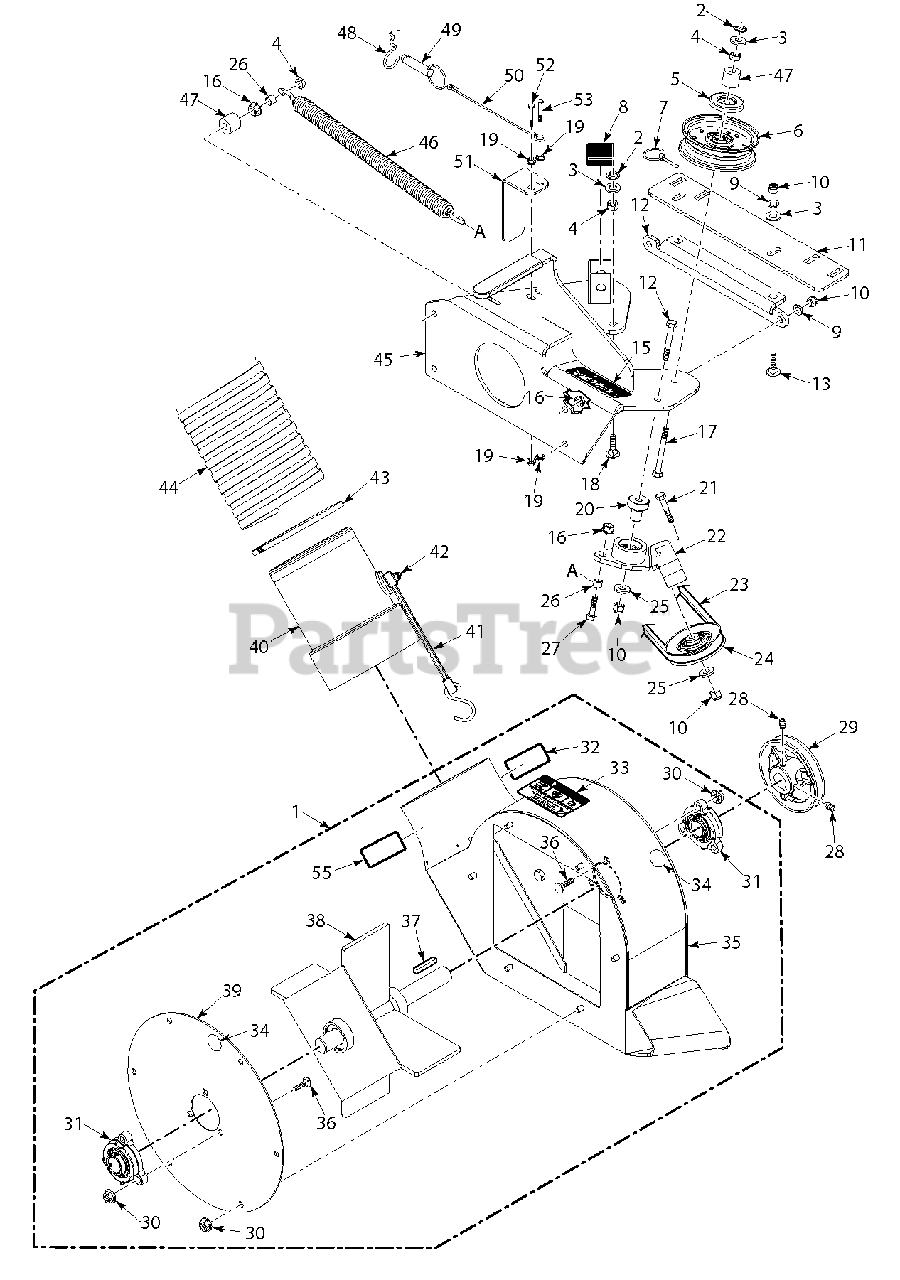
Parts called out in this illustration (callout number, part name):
1	Blowing Housing Assembly w/Fan
2	Nut, Push-On
3	Flatwasher, 3/8-.391 x .938 x .105
4	Nut, Center Lock 3/8-16
5	Dust Shield
6	Pulley, 4" Idler
7	Quick Pin
9	Lockwasher, 3/8" Spring
10	Nut, Elastic Stop 3/8-16
11	Plate, Blower Catch
12	Plate, Catch Mounting
13	Bolt, Carriage 3/8-16 x 1-1/4"
14	Bolt, Hex Head 3/8-16 x 2-1/4"
15	Decal, Belt Cover
16	Nut, Serrated Flange 3/8-16
17	Bolt, Hex Head 3/8-16 x 3-1/2" Full Thread
18	Bolt, Carriage 3/8-16 x 1-1/2"
19	Nut, Serrated Flange 1/4-20
20	Pivot, Idler
21	Bolt, Hex Head 3/8-16 x 2"
22	Idler Arm Assembly
22	Bearing
23	Belt (52)
23	Belt (61)
24	Pulley, 3-1/2" V-Groove
25	Flatwasher, 3/8-.391 x .938 x .105 HD
26	Sleeve
27	Bolt, Hex Head 3/8-16 x 1-1/4"
28	Set Screw
29	Pulley, 4-3/4" Dia.
30	Nut, Serrated Flange 5/16-18
31	Bearing Assembly
32	Decal, Blower
33	Decal, Danger
34	Decal, Grease Point
35	Blower Housing Weldment w/Decals
36	Bolt, Carriage 5/16-18 x 1"
37	Key, 1/4 x 1/4 x 1-1/2"
38	Fan Weldment, Narrow
39	Cover, Blower Housing
40	Adapter w/Strap
41	Rubber Strap
42	Bolt, Hex Head 1/4-20 x 1-1/4"
42	Nut, Elastic Stop 1/4-20
42	Flatwasher, 1/4-.312 x .750 x .065
43	Clamp, 6-1/2"
44	Hose, 6" x 56"
45	Blower Mounting Frame w/ Decal
46	Spring
47	Spacer
48	Hair Pin
49	Pin, Ring
50	Lanyard
51	Belt Cover
52	Bolt, Hex Head 1/4-20 X 1-1/2"
53	Bolt, Hex Head 1/4-20 x 1-1/4"
55	Decal, Rotating Blades
